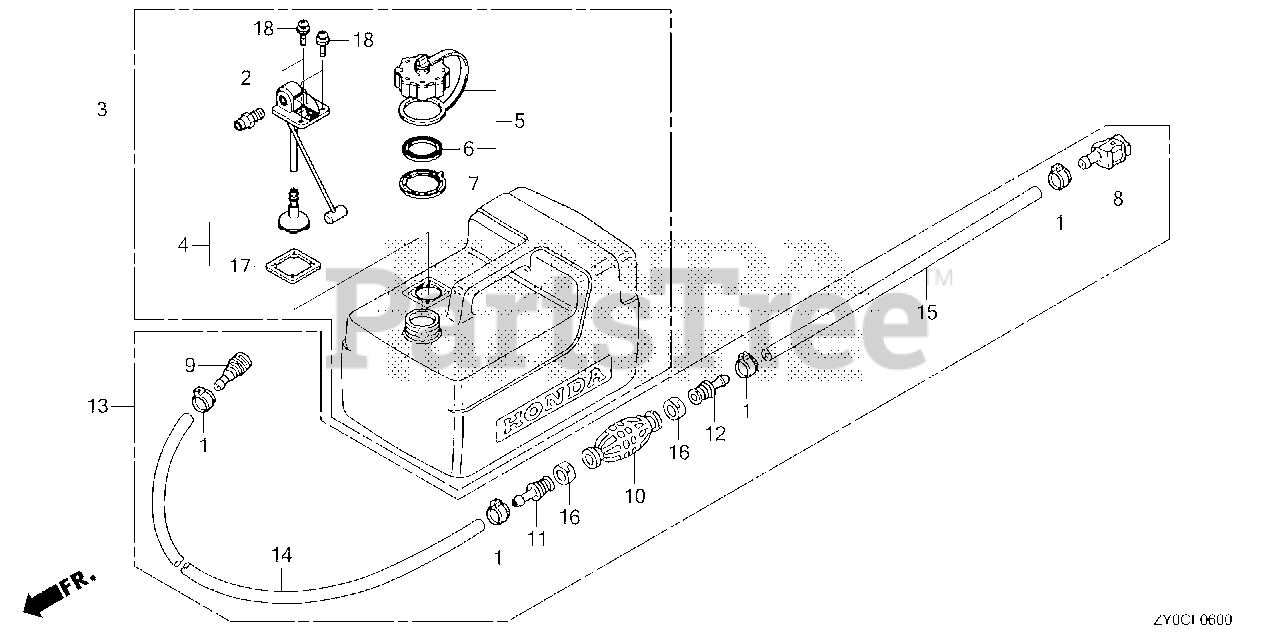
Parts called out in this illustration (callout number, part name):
1	CLAMP, FUEL TUBE (14.0)
2	FITTING, QUICK DISCONNECT
3	TANK ASSY., FUEL
4	FILTER KIT, FUEL
6	GASKET, FUEL CAP
7	RETAINER, PRESSURE RELIEF
8	CONNECTOR ASSY., FUEL (A)
9	CONNECTOR, FUEL
10	BULB, PRIMER
11	VALVE, IN.
12	VALVE, OUTLET
13	TUBE ASSY., FUEL TANK
14	TUBE, FUEL LONG (7.3X2000)
15	TUBE, FUEL SHORT
16	BAND, TUBE CLIP (20MM)
17	GASKET, FUEL PICK-UP
18	BOLT-WASHER (5MM) (SEAL)
